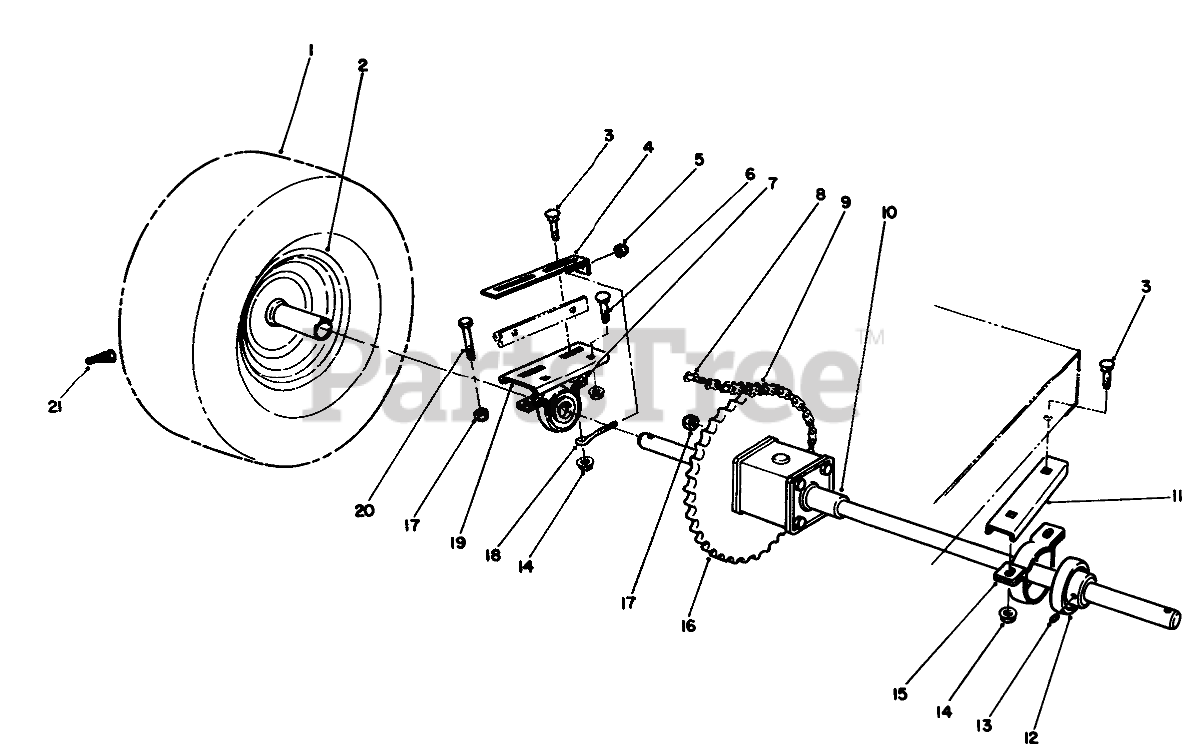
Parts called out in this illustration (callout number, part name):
1	TIRE,PNEU.13X5.00X6
2	WHEEL-REAR
3	BOLT-CARR
4	PLATE-ADJUSTING
5	NUT-LOCK, NI
6	SCREW-CARR
7	RTNR-PILLOW BLK
8	LINK-CHAIN
9	Chain (Incl. Ref. #8)
10	DIFFERENTIAL
11	Support L.H.
12	Bearing (Incl. Ref. #13)
13	SCREW-HSH
14	NUT-HF
16	45 T SPROCKET
17	NUT-LOCK, NI
18	SCREW-ADJUSTING
19	Support R.H.
20	Bolt
21	STEM-VALVE
